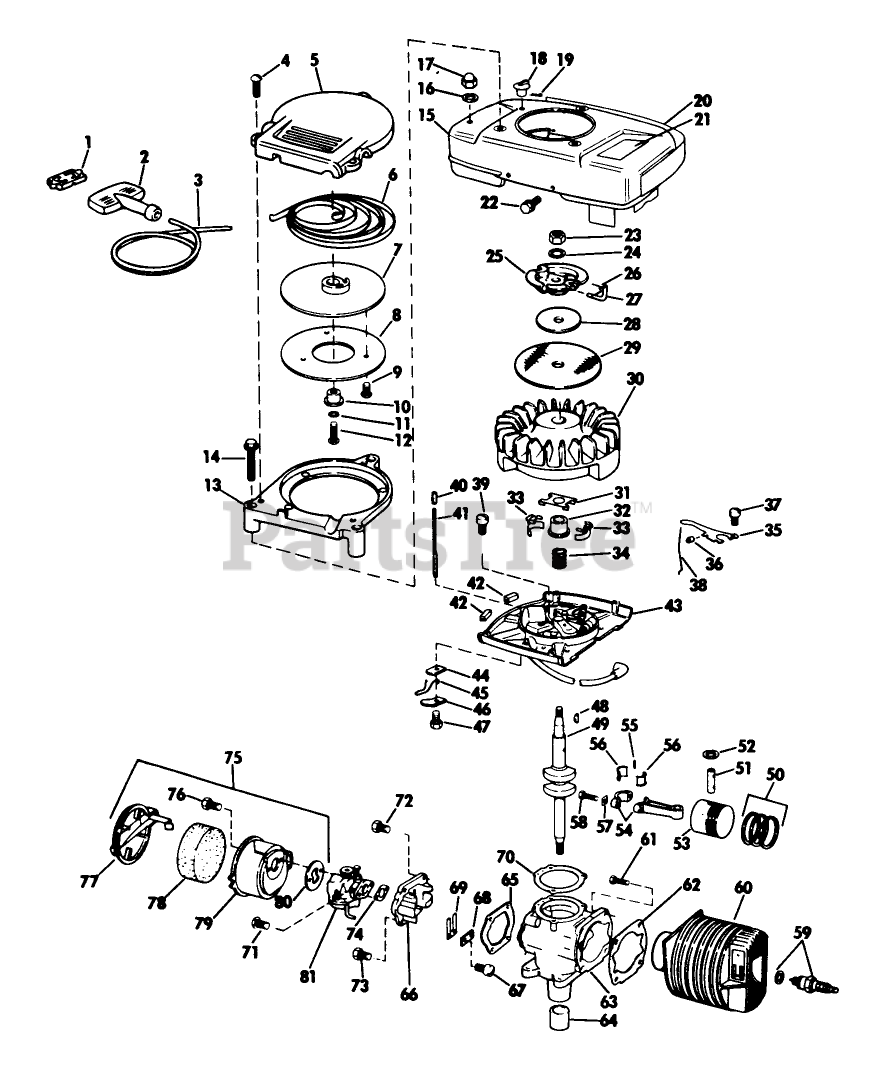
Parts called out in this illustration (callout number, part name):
6	RECOIL SPRING
17	PALNUT S
18	KNOB, CHOKE BAR
19	Cotter Pin-Choke Knob
22	SCREW S
27	PIN - STARTER
32	COLLAR S
35	GOVERNER LEVER AY
36	WEAR BLOCK S
38	GOVERNOR ROD S
47	Screw Shut-off Switch
52	RING-RETAINING
56	LINER ASM
62	GASKET S
68	PLATE-BACKUP, REED
70	GASKET S
72	SCREW S
73	SCREW S
74	GASKET S
76	SCREW S
78	AIR FIL.ELEM S
80	GASKET S
